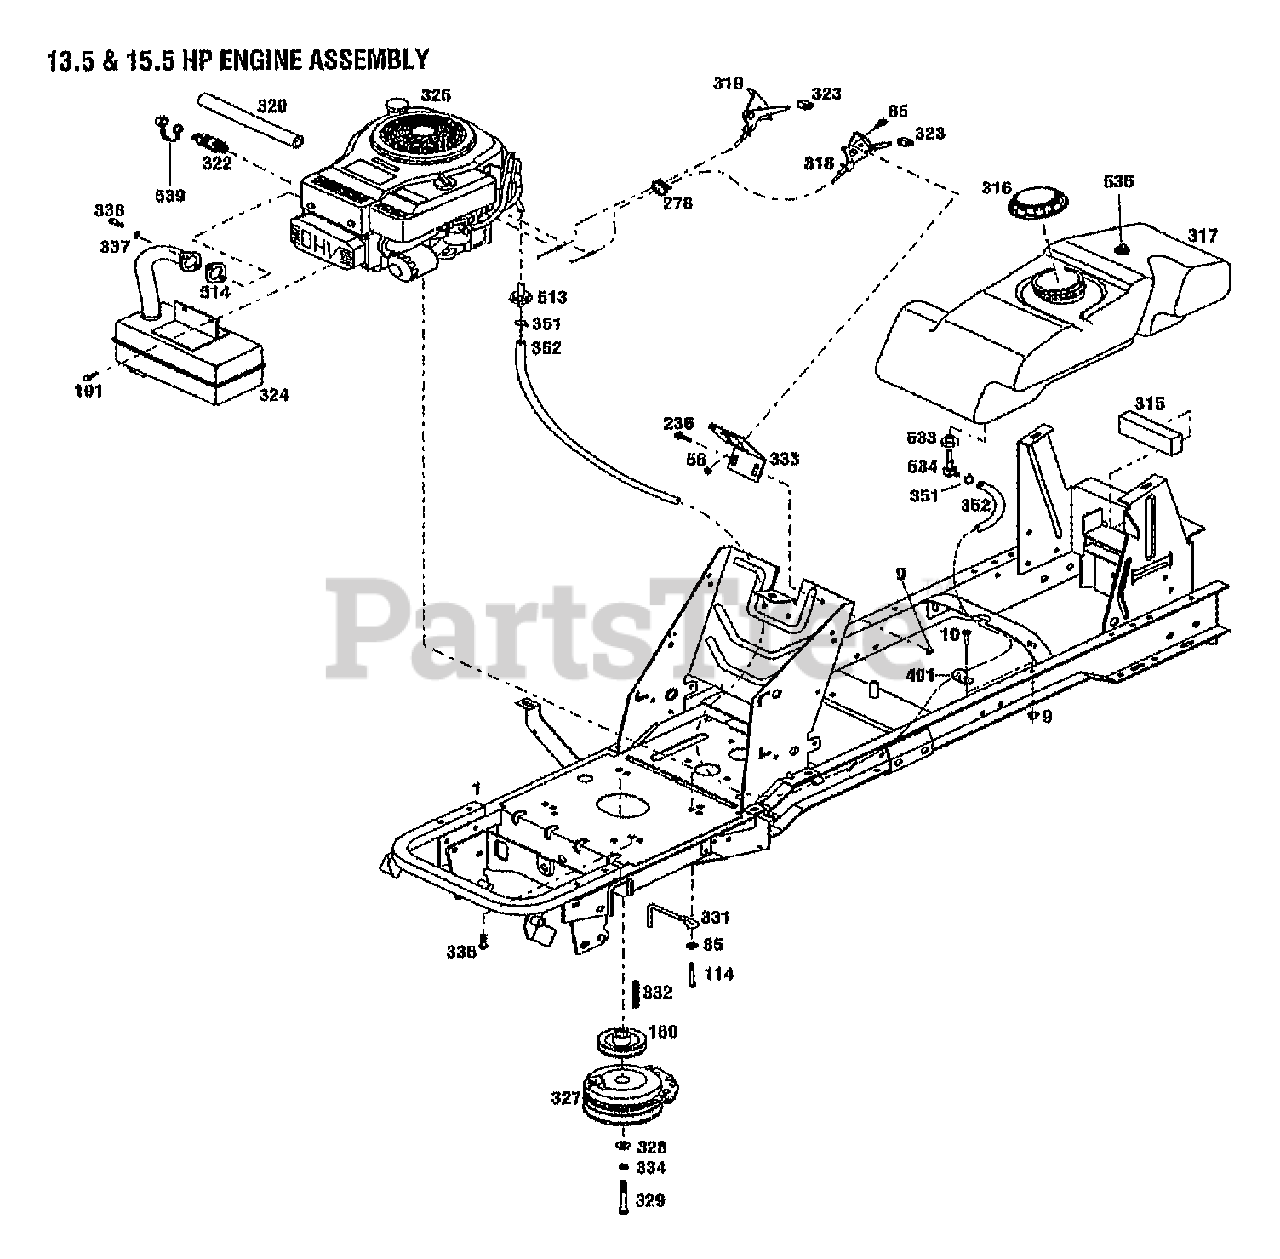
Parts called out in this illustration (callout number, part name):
1	ASSM-FRAME LTX
9	NUT-HFLK 5/16-18 ZP
10	SCR-HHC 5/16-18X.75 GR 5 ZP
56	NUT-HF/LK 1/4-20 ZP
85	WASHER-FLAT 3/8 SAE
114	SCR-THRD FRM 3/8-16X1.50
160	PULLEY-ENGINE
191	SCR-FLANGE 1/4-20X3/4 GR5
236	SCR-HFLK 5/16-18X.75 ZP
278	TIE-CABLE NYLON BLACK
315	PAD-FUEL TANK
316	CAP-FUEL
317	TANK-FUEL
318	CONTROL-THROTTLE
319	CONTROL-CHOKE
320	HOSE-OIL DRAIN
322	ASSM-OIL VALVE
324	MUFFLER
325	ENGINE, 13HP BRIGGS & STRATTON, MODEL 28M707
325	ENGINE, 15.5HP BRIGGS & STRATTON, MODEL 28N707
327	CLUTCH-ELECTRIC
328	WASHER-SPEC 1.42X.468X.25 ZP
329	SCR-HH 7/16-20X3.00
331	CLUTCH-RETAINER
332	KEY-.25 SQ X 2.5
333	BRKT-MOUNTING CONTROL
334	WASHER-LK .438 ZP
335	SCR-HH 3/8-16X1.0 THDFM
337	WASHER-LOCK
338	SCR-HXSKT 5/16-18X.75 BO
351	CLAMP-HOSE
352	LINE-FUEL
401	CLAMP-WIRE
513	FILTER-FUEL
514	MUFFLER GASKET
533	BUSHING-RUBBER
534	ELBOW-90 DEG (FUEL LINE)
535	VENT-FUEL TANK
539	CAP-OIL DRAIN
